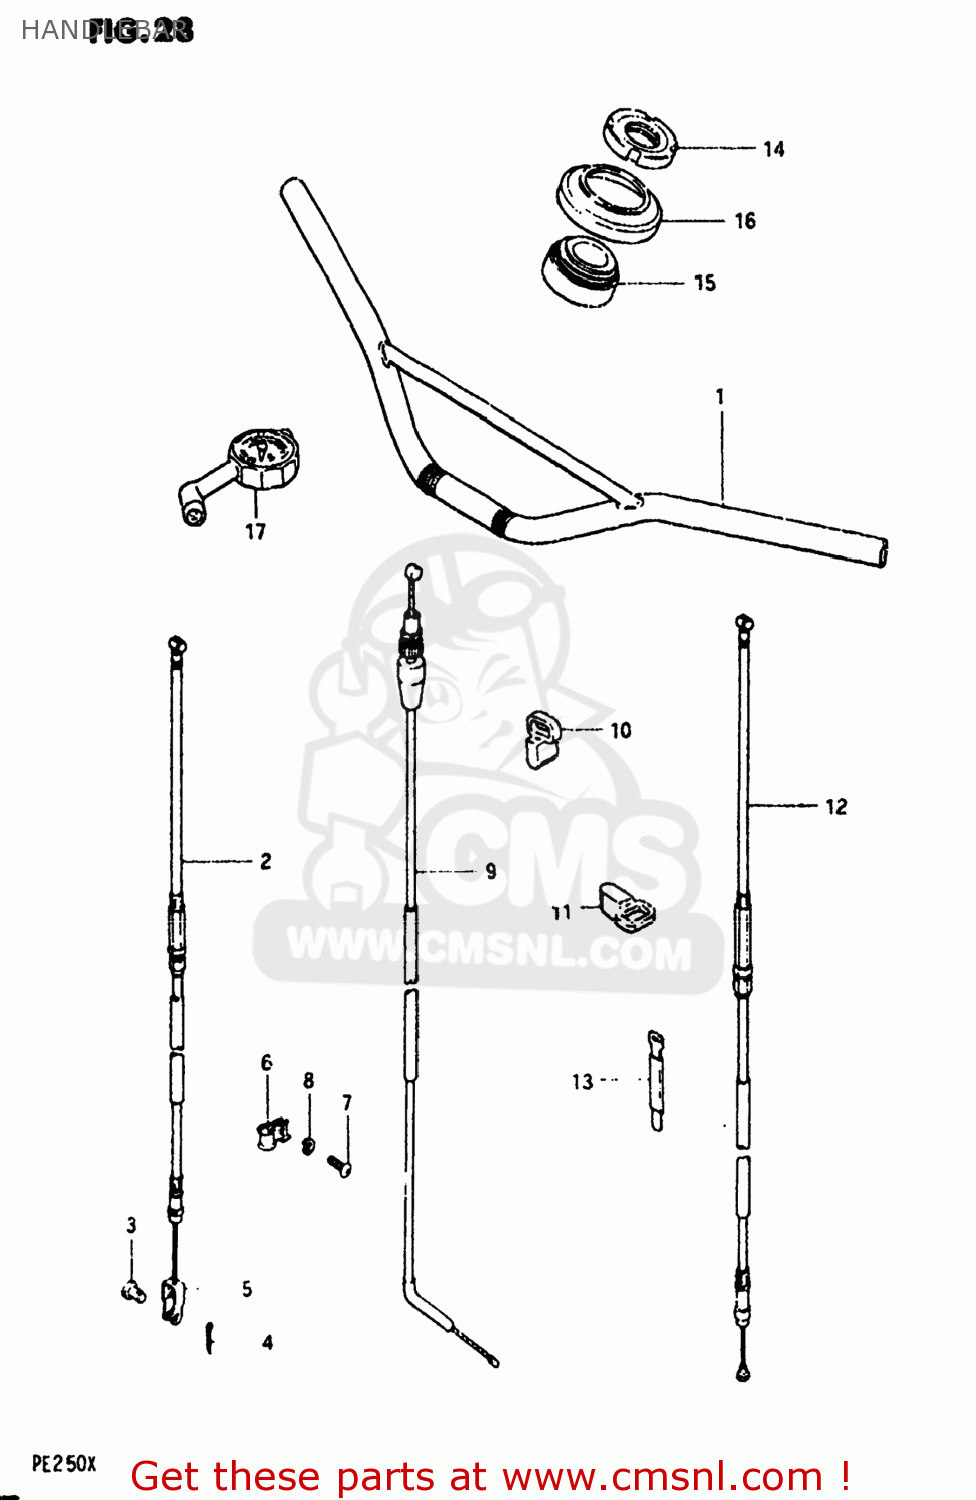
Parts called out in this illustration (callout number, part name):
1	HANDLEBAR
2	CABLE,FRONT BRAKE
3	PIN(L:13.5)
4	PIN
5	BRAKE CABLE HOOK
6	GUIDE,CABLE
7	SCREW
8	LOCK WASHER
9	CABLE ASSEMBLY,THROTTLE
10	GUIDE,CABLE
11	GUIDE,CLUTCH CABLE
12	CABLE,CLUTCH
13	CLAMP
14	NUT,STEERING STEM(25X44X10)
15	TAPER,ROLLER BEARING
16	DUST SEAL,STEERING,UPPER
17	GAUGE ASSY,AIR PRESSURE
